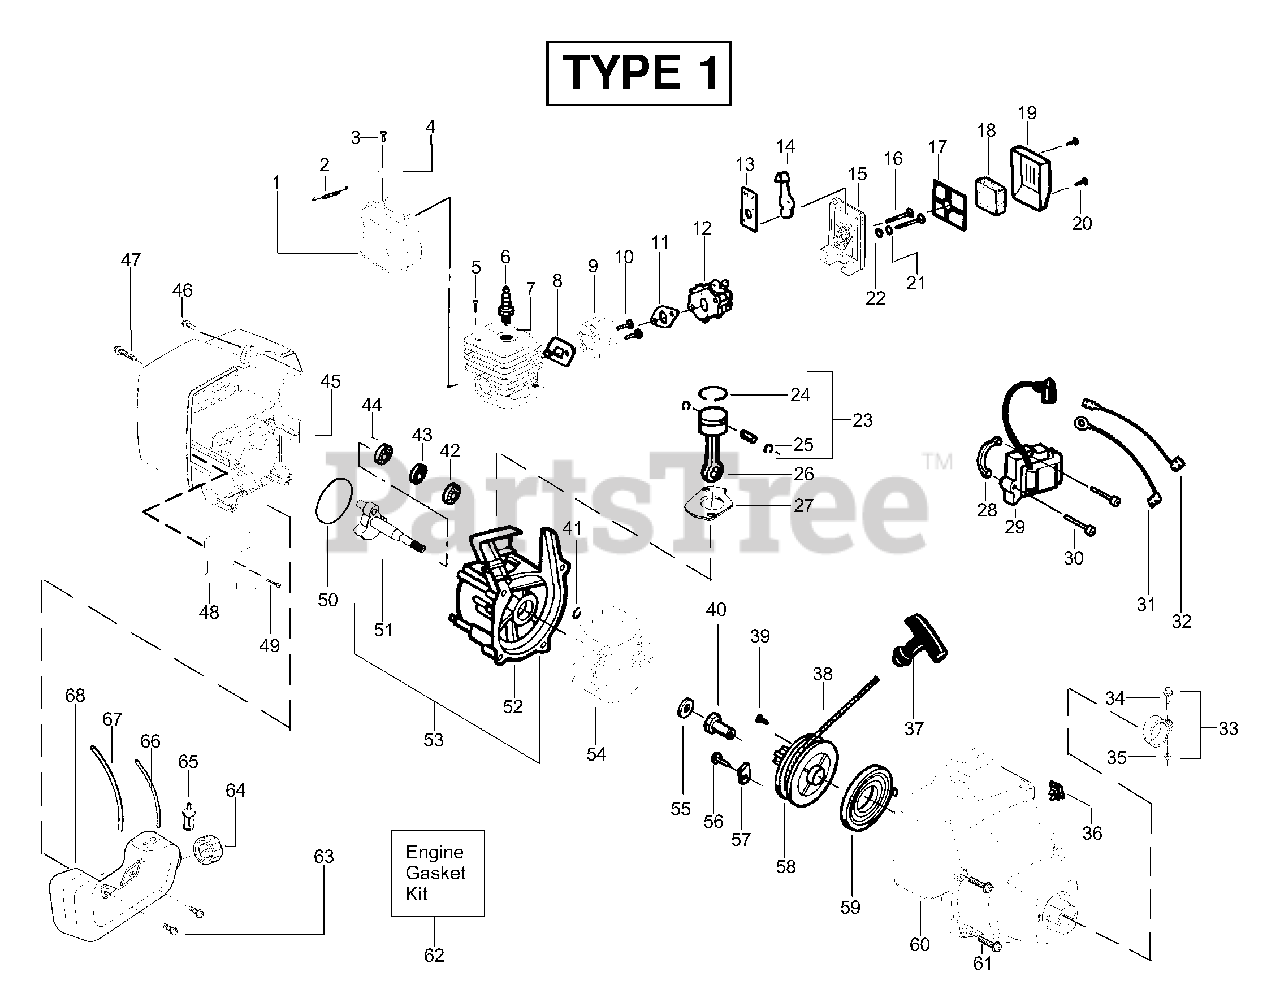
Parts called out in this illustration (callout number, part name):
1	Kit - Muffler
2	Spring-Muffler
3	Screw-Screen
4	Kit-Spark Arrestor
5	Screw-Cylinder
6	Spark Plug (RCJ 6Y)
7	Kit - Cylinder
8	Gasket-Cylind./Carb.
9	Adapter-Carb.
11	Gasket-Carb.
12	Kit - Carburetor Ass'y (C1U-W10)
12	Kit - Carburetor Ass'y (C1U-W10B)
13	Choke Plate Mounting
14	Shutter-Choke
17	Plate - Filter Support
18	Foam-Air Filter
19	Cover-Air Filter
21	Spacer-Choke
23	Kit - Piston
24	Piston Ring
25	Retainer-Piston Pin
26	Assy-Connecting Rod
27	Gasket-Cylinder
28	Spacer-Module
29	Ignition Module
31	Assy-Ground Wire
32	Assy-Leadwire
33	Assy-Nose Cone Clamp
34	Screw-Nose Cone
35	Nut-Nose Cone
36	Kit-On/Off Switch
37	Handle-Starter
38	Kit - Rope
40	Coupling-Drive
41	Retain. Ring-C'shaft
42	Outer Bearing
43	Kit-C'case Seal
44	Inner Bearing
45	Shroud-Rear
47	Screw
48	Shield-Heat
49	Screw
50	O-Ring-C'case/Shrd
51	Assy-Crankshaft
52	Assy-Crankcase
53	Assy-C'case & C'shaft
54	Assy-Flywheel
55	Washer-Flat
57	Retainer-Can
58	Kit-Starter Pulley
59	Spring-Starter
60	Assy.-Fan Hsg
61	Screw
62	Kit-Engine Gasket
63	Retainer
64	Assy-Fuel Cap
65	Assy-Fuel Pickup
66	Kit-Fuel Line (Small)
67	Kit-Fuel Line (Large)
68	Assy-Fuel Tank
